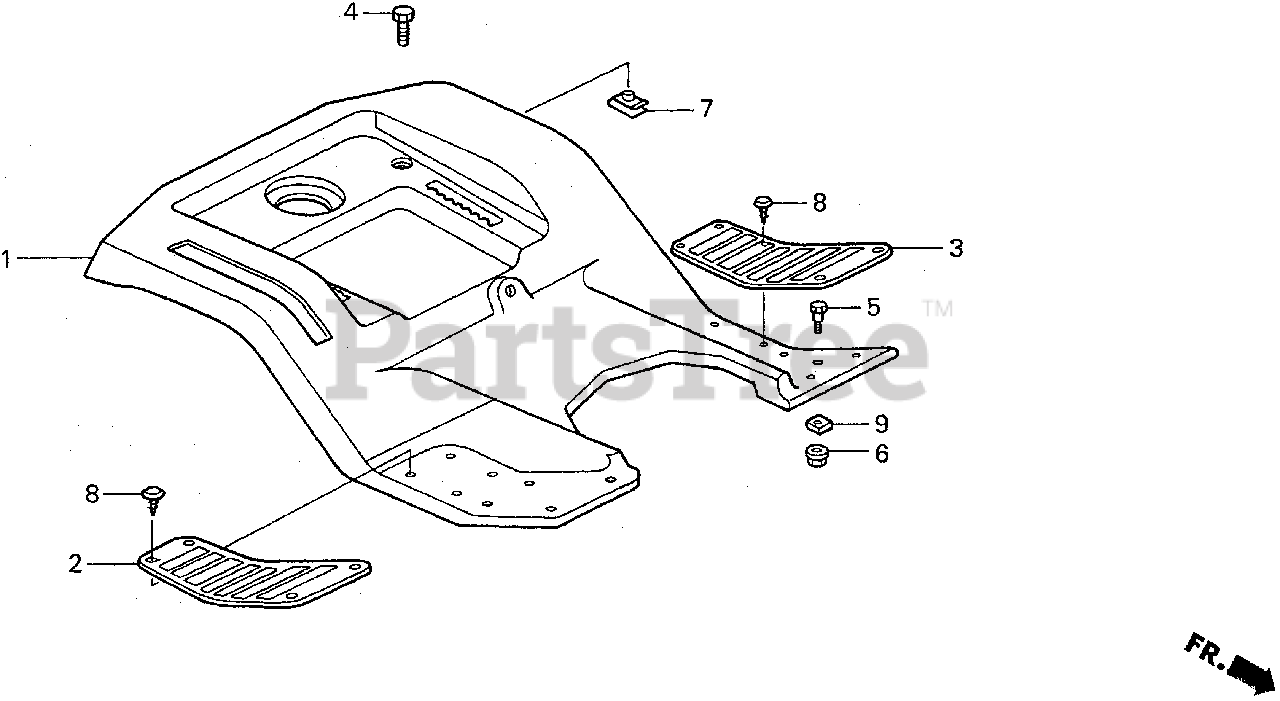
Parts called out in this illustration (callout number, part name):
1	FENDER, RR.
2	FLOOR MAT, R.
3	FLOOR MAT, L.
4	BOLT, HEX. (8X20)
5	BOLT, CARRIAGE (8X20)
6	NUT, FLANGE (8MM)
7	NUT, SPECIAL (8MM)
8	CLIP, PLATFORM PUSH
9	RETAINER, FRAME
